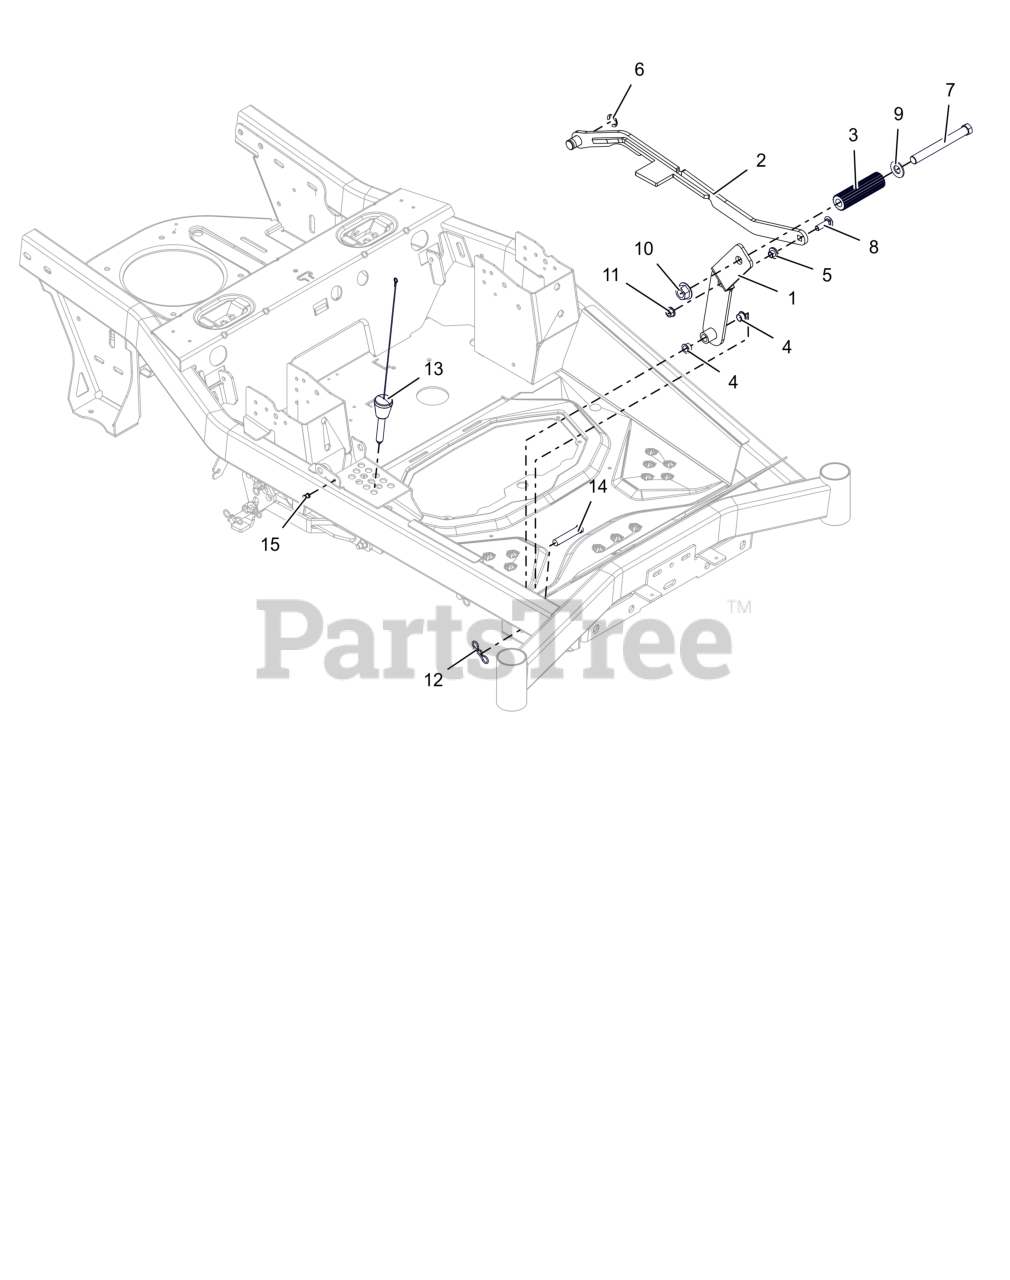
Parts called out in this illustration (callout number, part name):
1	WLDMT- FOOT PEDAL-ORG
2	LINK- DECK LIFT-ORG
3	ROD, FOOT PEDAL (BLACK)
4	BUSHING, POLYLINER-.50 SPLIT
5	BSHG-FLG .385X.500X.875X.406
6	E-RING .750X.050
7	BLT, HEX .62-11X5.50 G5 FBP
8	BLT,RHSSN .38-16X1.25 G5 ZCC
9	WSHRFLT 5/8SAE CARBHARD FBP
10	NUT,FLG-TOP LK .625-11 FBP
11	NUT-LK-CTR-FLG .375-16 GF ZCC
12	PIN, BOWTIE .091X1.875 ZCC
13	PIN- MAGNETIC .50X2.70
14	PIN-CLEV .494X2.50 BRIGHT ZINC
15	POST, & SCREW, PUSH LOCK .25 X .25
